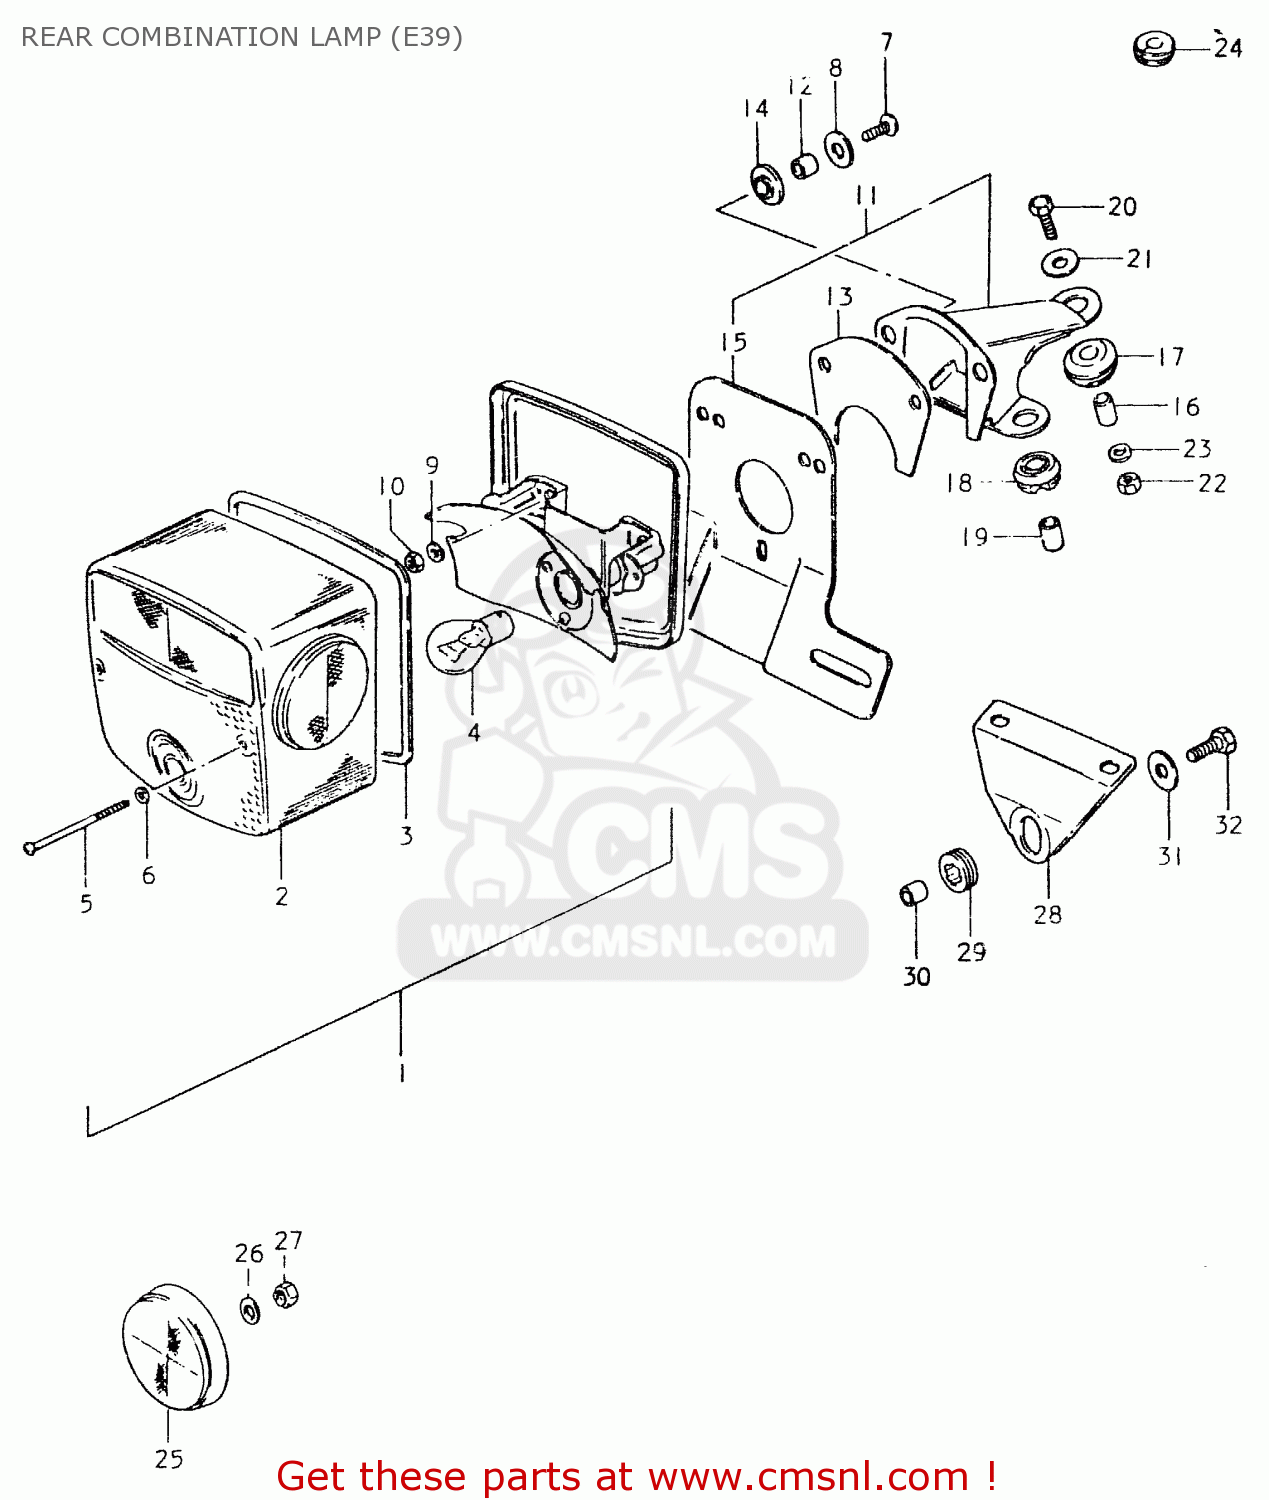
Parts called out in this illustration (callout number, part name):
1	LAMP UNIT, TAIL
2	LENS
3	GASKET (NAS)
4	BULB (6V,21/5W)
5	SCREW (4X55)
6	GASKET (NAS)
7	TAPPING SCREW
8	WASHER,REAR COMBINATION LAMP
9	NUT
10	LOCK WASHER
11	BRACKET SET
12	SPACER
13	CUSHION
14	CUSHION,REAR COMBINATION LAMP
15	PLATE, LICENCE
16	SPACER
17	CUSHION,REAR COMBINATION LAMP
18	CUSHION,REAR COMBINATION LAMP
19	SPACER
20	BOLT
21	WASHER (6.5X20X1.2)
22	NUT
23	WASHER 6MM
24	GROMMET
25	REFLEX REFLECTOR,FR
26	WASHER
27	LOCK WASHER
28	REINFORCEMENT
29	CUSHION
30	SPACER (6.1X9X9)
31	WASHER (6.5X20X1.2)
32	BOLT, UPPER
